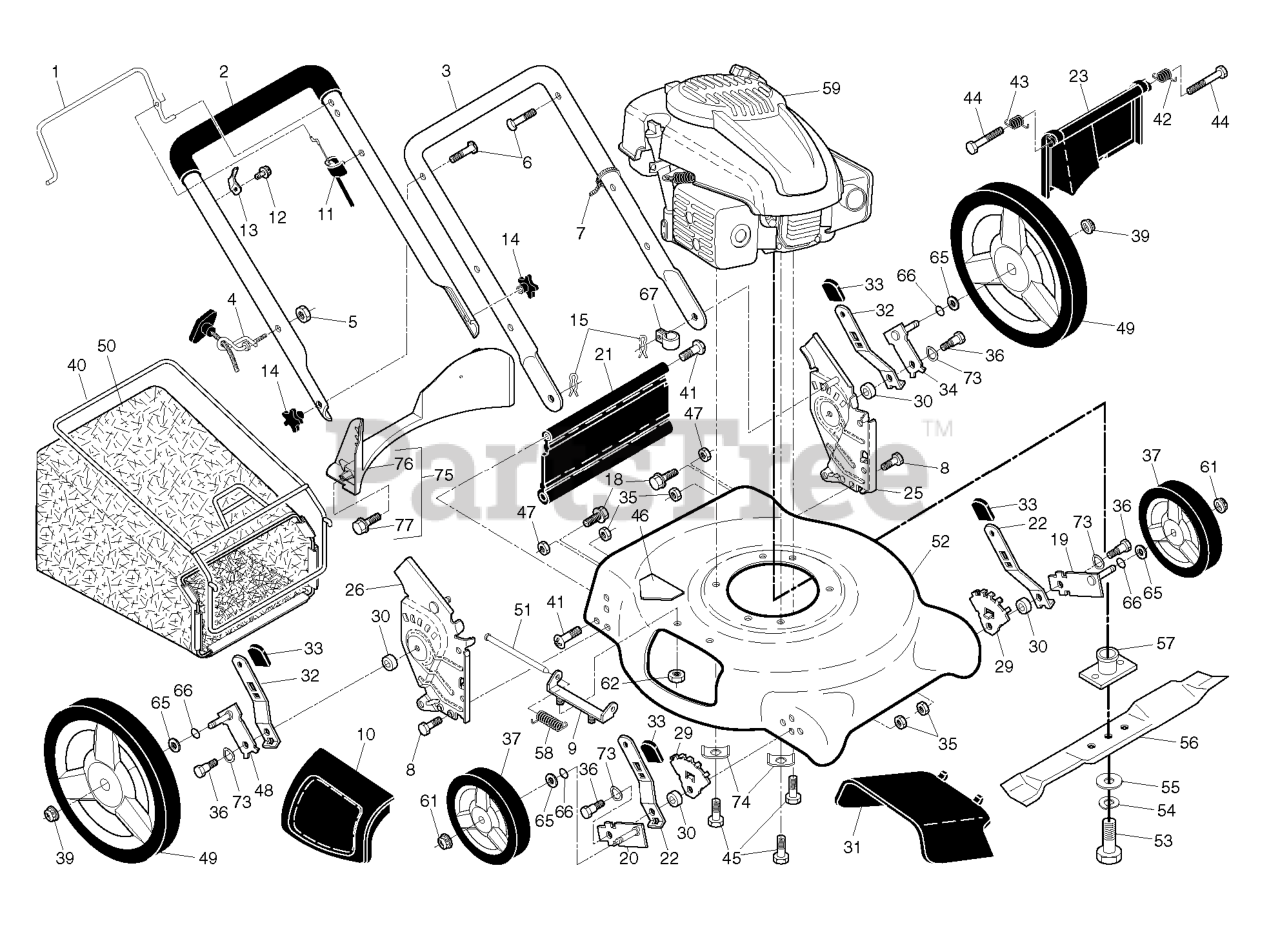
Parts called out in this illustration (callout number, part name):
1	BAIL.MZR.STD.ORANGE
2	UPPERHANDLE(INCLUDES FOAMGRIP)
3	HANDLE.LOWER.GREY
4	RB GUIDE.ROPE.STD.BLK.ZIN WSL
5	NUT
6	BOLT, HANDLE 5/16-18X1.75
7	TIE GUIDE
8	BOLT.FIN.HEX.5/16-18X3/4
9	BRACKET.ASM.HOUSING.EZ.MUL
10	RP DOOR.MULCH.21".REAR.PUSH.GR
11	CABLE.ENGINE.ZONE.CONTROL
13	BRACKET.UPSTOP.RT
14	KNOB.HANDLE.PLASTIC.STAR.BLACK
15	HAIRPIN COTTER
18	SCREW 1/4X20
19	AXLE ARM ASSY FRONT LH
20	AXLE ARM ASSY FRONT RH
21	RP_KIT.SKIRT.21 DOMED.W/LIP
22	SELECTOR SPRING, FRONT
23	REAR DOOR ASSY
25	RP BRKT.ASM.HAND.HW.21.LT.ORNG
26	RP BRKT.ASM.HAND.HW.21RT.ORNG
29	WHEEL ADJ BRACKET FRONT
30	SPACER.HEIGHT.ADJUSTER
31	DEFLECTOR.CLIPPING.21.GREY
32	SPRING.SEL.EXT.21.DOMED.12/14
34	AXLE ARM ASSY REAR LH
35	NUT.FLANGE.HEX.5/16X18.BLACK
36	SHOULDER BOLT 5/16-18
37	WHEEL AND TIRE ASSY, REAR
39	NUT.HEX.FLANGE.3/8-16.LOCKNUT
40	FRAME.BAG.21.REAR.DOMED.PUSH
41	HINGE SCREW
42	SPRING.LH.22.REAR.DOOR.EZ.EMPT
43	SPRING.RH.22.REAR.DOOR.EZ.
45	BOLT 3/8-16X1-1/8
46	DANGER DECAL
47	NUT.LOCK.5/16-18
48	AXLE ARM ASSY REAR RH
49	WHEEL ASSY
50	GBAG.2323247.SILVER
51	ROD.HINGE.COMBI-C
52	RP KIT.HSG.
53	SCREW, HEX HD 3/8-24 X 1-3/8
54	LOCKWASHER
55	WASHER,HARDEN
56	BLADE.21.PUSH/RWGD/FWGD
57	ADAPTER.BLADE.W/KEY.25MM.CE
58	TORSION SPRING
61	NUT.HEX.FLANGE.3/8-16.LO(3 2)
62	LOCKNUT.NYLOC.1/4-20
65	WASHER.FLAT.1/2
66	O-RING..070X.487.NEOPRENE
67	CLIP.CABLE.BLK
73	WASHER.CURVED.CYLINDRICAL
74	WASHER.ENGINE.BZP
75	KIT.BAFFLE.REAR.PLASTIC.21.RD
76	BAFFLE.REAR.PLASTIC.21.RD.ECON
77	SCREW.HX.13X.750
